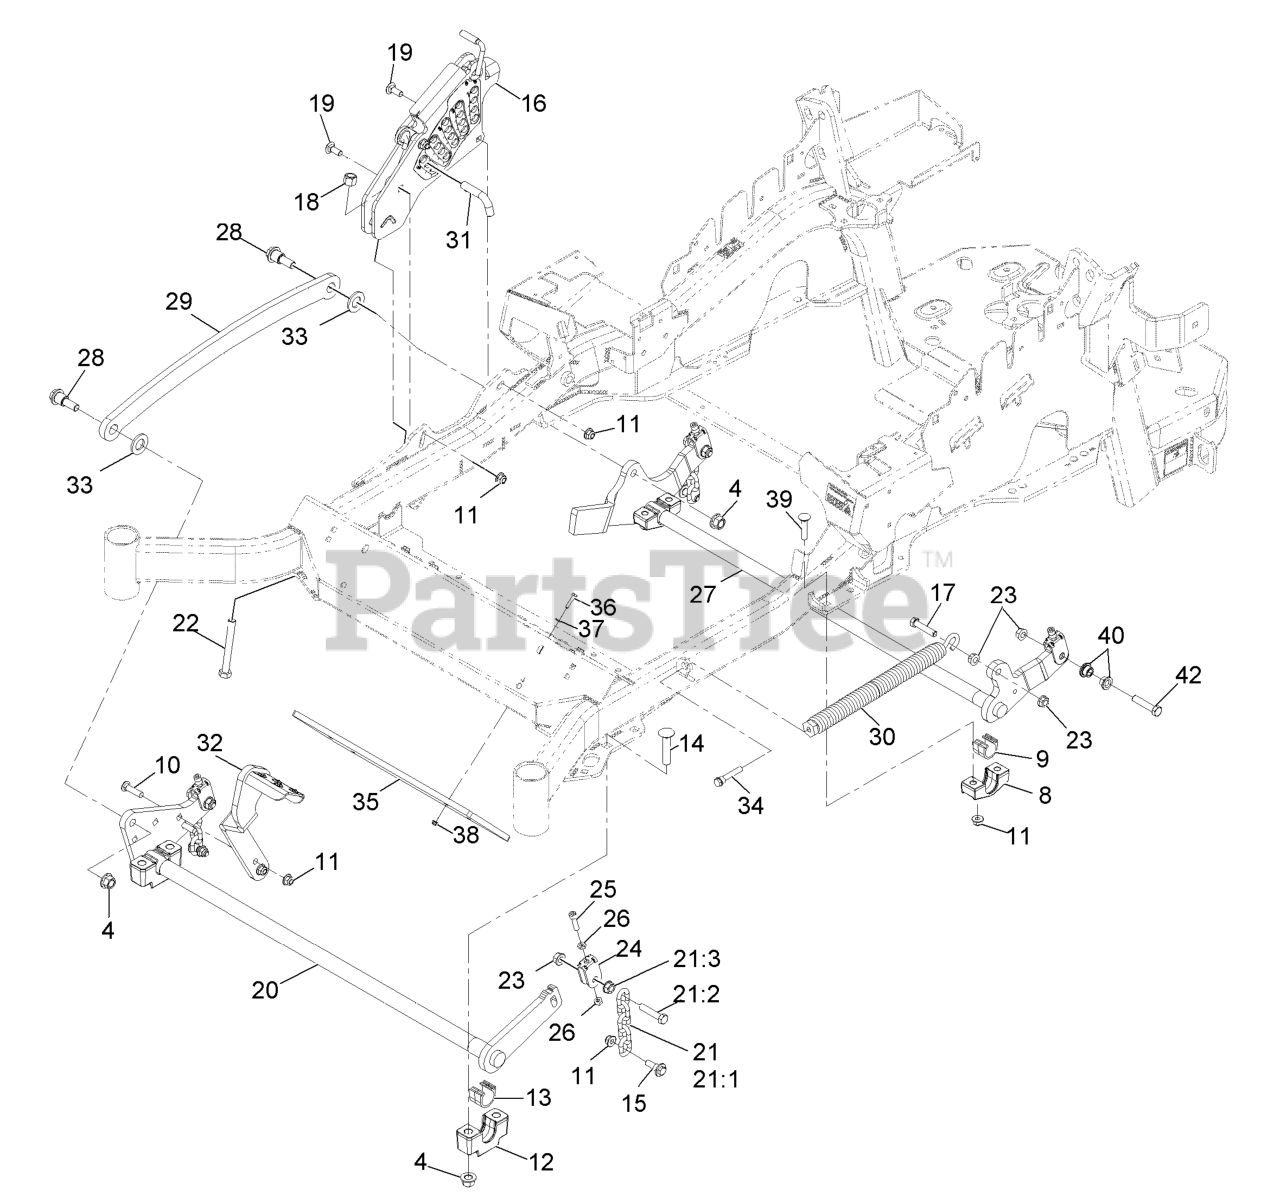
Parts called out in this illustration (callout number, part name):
4	Nut-Lock 1/2-13
9	BEARING-CROSS SHAFT, REAR
10	SCREW-CARR
11	NUT-HF, NI
12	SUPPORT-CROSS SHAFT, BEARING
13	BEARING-CROSS SHAFT, FRON
14	Bolt-Carriage 1/2-13 X 2 1/2 Spl Neck
15	SCREW-SHOULDER, HHF
16	HOC ASM
17	SCREW-HH
18	NUT-LOCK, NI
19	BOLT-CARR
21	DECK LIFT CHAIN ASM
21:1	CHAIN-LIFT, DECK
21:2	SCREW-HH
22	BOLT-TAP
24	YOKE-ADJUST, DECK
25	SCREW-HH
26	NUT-JAM
27	LIFT-DECK, REAR
28	SCREW-SHOULDER, HHF 1/2-13 X 1.12
29	LINK-LIFT, DECK
30	SPRING-EXTENSION
31	PIN-HOC
32	LEVER-FOOT
33	WASHER-FLAT
34	BOLT-SHOULDER
35	WEIGHT,TOE BOARD
36	SCREW-HH
37	WASHER-FLAT
39	SCREW-CARR
40	BUSHING-FLANGED
42	SCREW-HH
